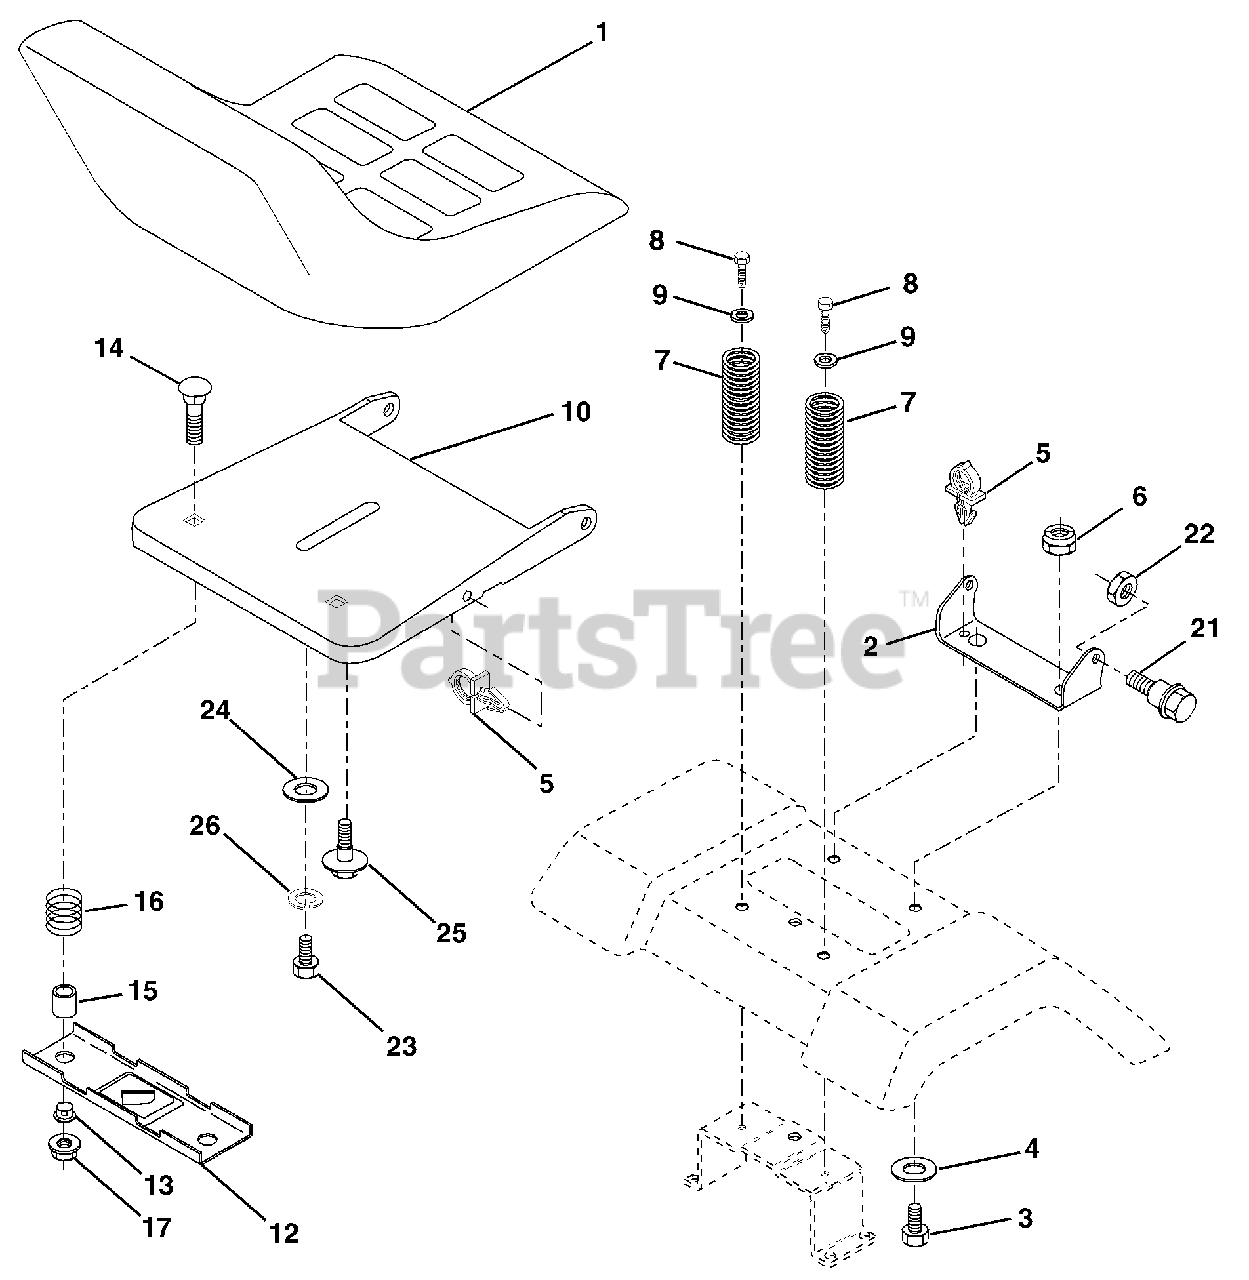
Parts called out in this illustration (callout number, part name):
1	Seat
2	Bracket Pnt Pivot Seat (blk)
3	Bolt
4	Washer 13/32 x 1 x 10 Ga.
5	Clip Push-In Hinged
6	Nut
7	Spring Seat Cprsn 2 250 Blk Zi
8	Screw 3/8-16 x 1.5
9	Washer 13/32 x 1 x 14 Ga.
10	Pan Pnt Seat (blk )
12	Bracket Pnt Mounting Switch
13	Bushing Snap Blk Nyl 50 Id
14	Bolt Rdhd Sht Nk 1/4-20 x 1-1/2
15	Spacer Split 28 x 96 Yel Zinc
16	Spring Cprsn 1 27 Blk Pnt
17	Nut Lock 1/4 Lge Flg Gr. 5 Zinc
21	Bolt Shoulder 5/16-18 unc Blkz-2A
22	Nut
23	Bolt Hex Black
24	Washer 17/32 x 1-3/16 x 12 Ga.
25	Bolt Shoulder 5/16-18 x 62
26	Lockwasher
